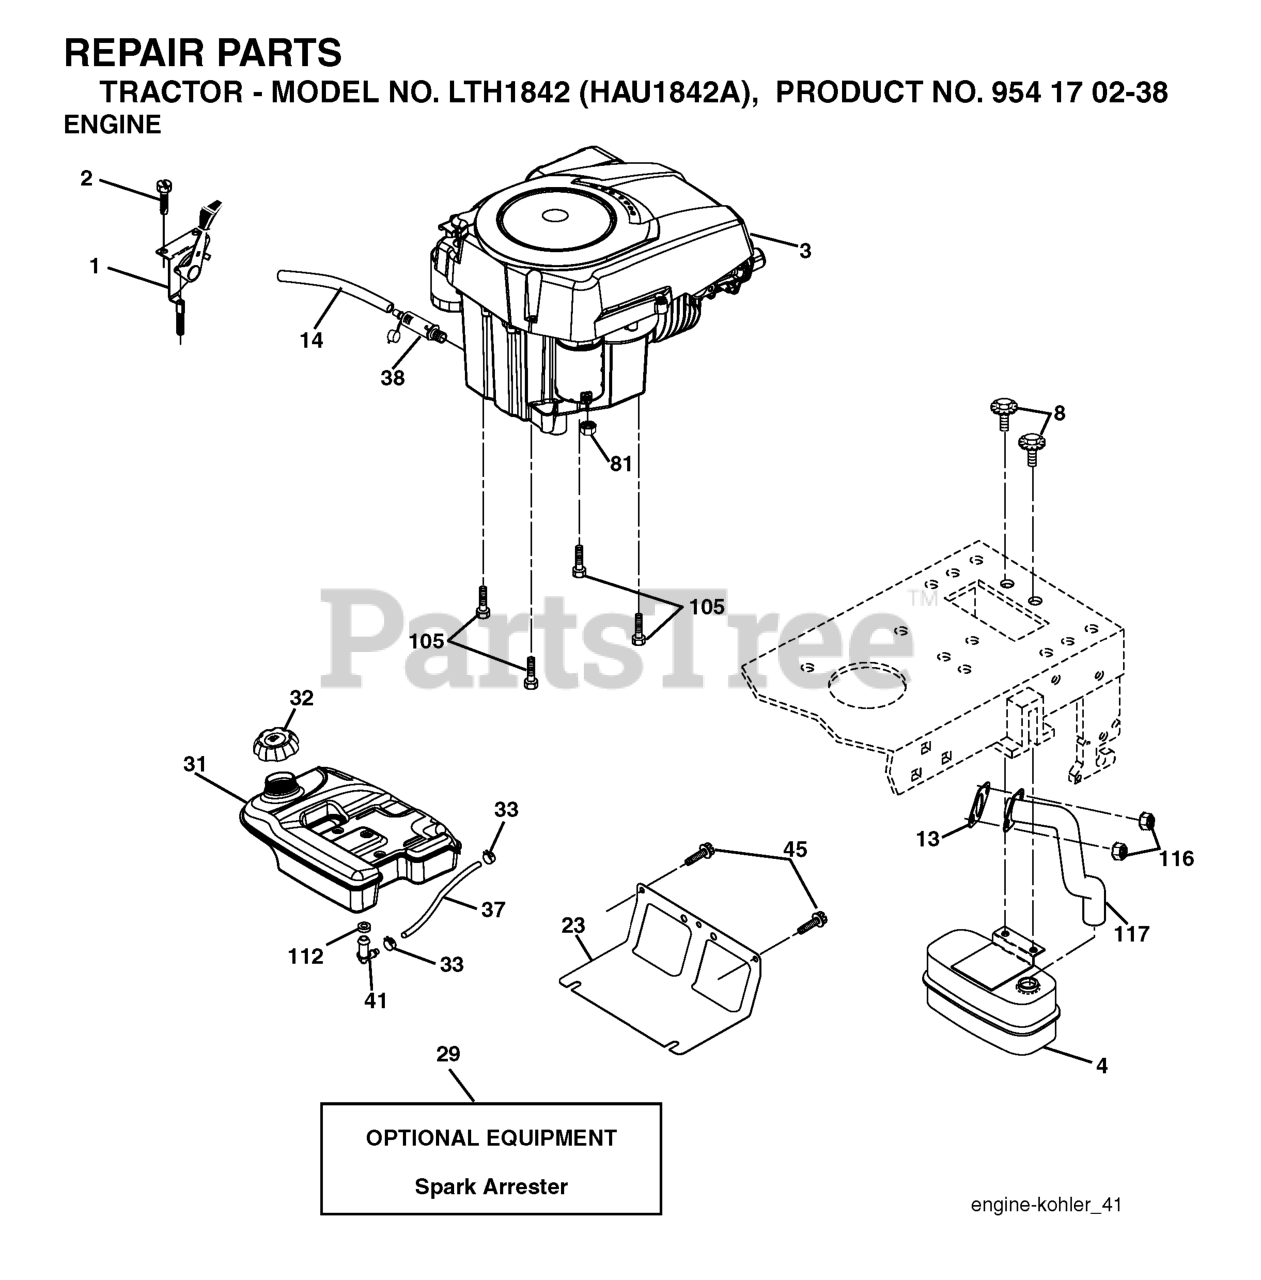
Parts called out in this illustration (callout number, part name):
1	CONTROL.THROTTLE.LT/YT
2	SCREW
4	MUFFLER.SINGLE.CYL.KOHL/B&S
8	BOLT.5/16-18UNCX3/4 W/SEMS.BLK
13	GASKET.EXHAUST.KOHLER
14	TUBE, DRAIN OIL ASM.
23	SHIELD.BROWNING.DBR.GUARD
29	KIT.SPARK ARRESTOR 794945 B&S
31	4.0 REAR FUEL TANK
32	TANK CAP
33	HOSE CLAMP
37	REPL BY 532 00 85-43
38	PLUG DRAIN OIL EASY
41	STEM FUEL TANK
45	SCREW, 3/8-16X3/4
81	NUT
105	SCREW 3/8-16X1
112	BUSHING OUTLET T
116	NUT.HEX.FLANGE.TOPLOCK
117	RP.TUBE.EXHAUST.KOHL.COURAGE
